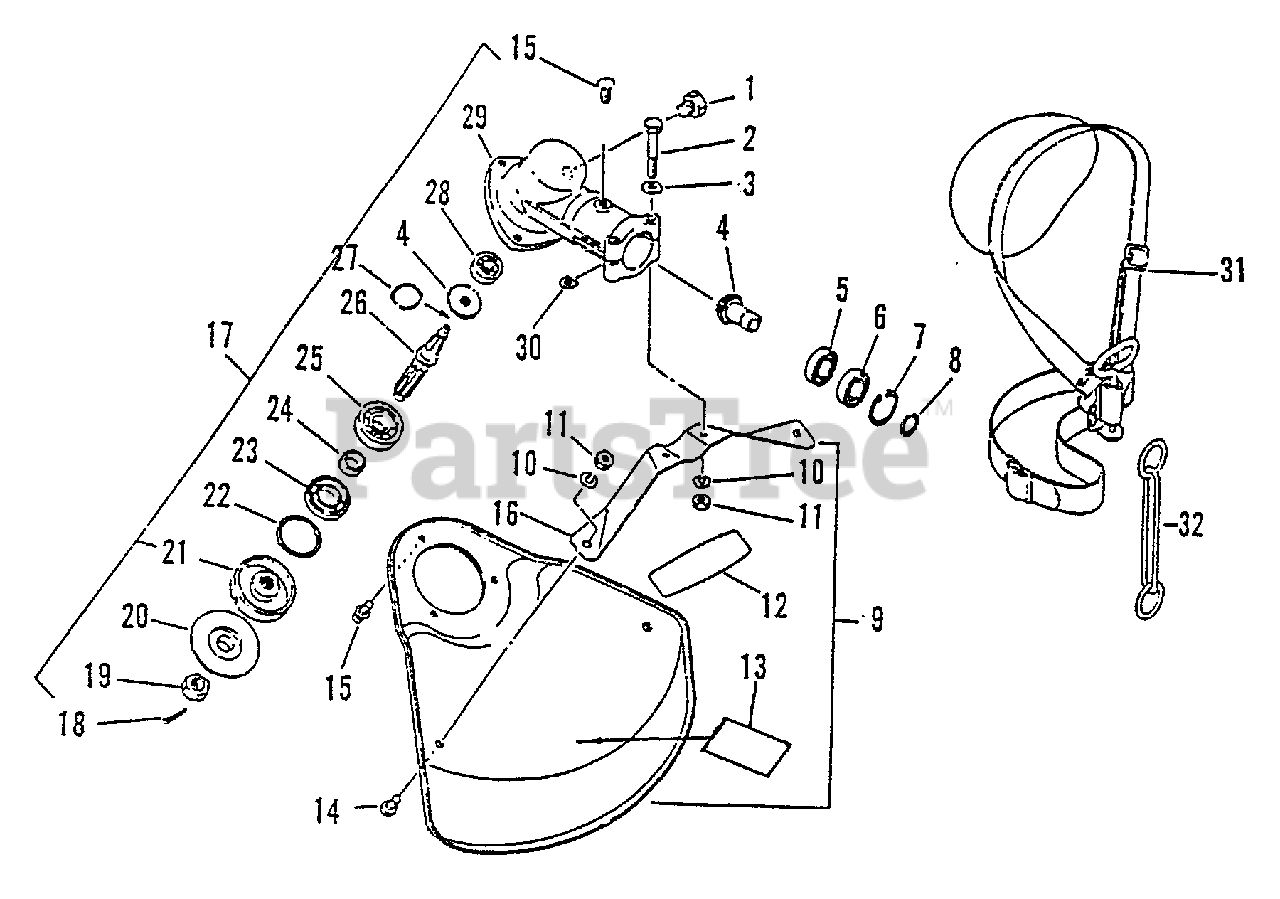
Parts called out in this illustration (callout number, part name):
1	BOLT - 8X8
2	BOLT - 5X35
3	WASHER - 5
4	GEAR SET - BEVEL
5	BEARING, BALL - 6900
6	BEARING, BALL - 6900Z
7	RING, RETAINING - 22
8	RING, RETAINING - 12
9	DEBRIS SHIELD KIT - METAL
10	LOCKWASHER - 5
12	LABEL - ECHO
13	LABEL - CAUTION
14	SCREW - 5X8
15	SCREW - 5X10
16	BRACKET, SHIELD
17	GEAR CASE ASSY
18	PIN, SPLIT - 2X22
19	NUT - 10 -- LEFT HAND
20	ADAPTOR, BLADE - LOWER
21	ADAPTOR, BLADE - UPPER
22	RING, RETAINING - 32
23	SEAL, OIL
25	BEARING, BALL - 6201
26	GEAR - SHAFT
27	RING, RETAINING - 10
28	BEARING, BALL - 609
29	CASE, GEAR
31	SHOULDER STRAP ASSY
